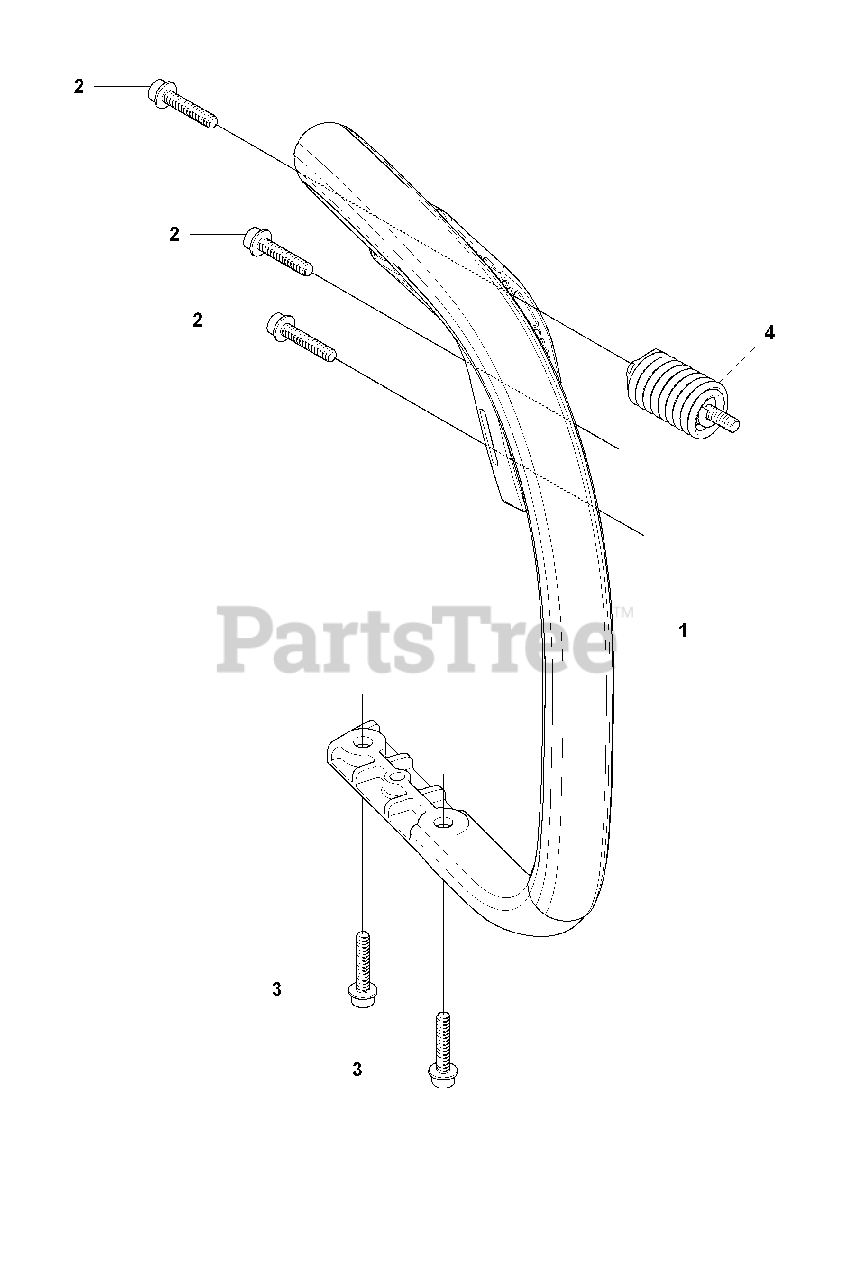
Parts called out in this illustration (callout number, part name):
1	FRONT HANDLE
2	SCREW IHSCFT
3	SCREW
4	INSULATOR
